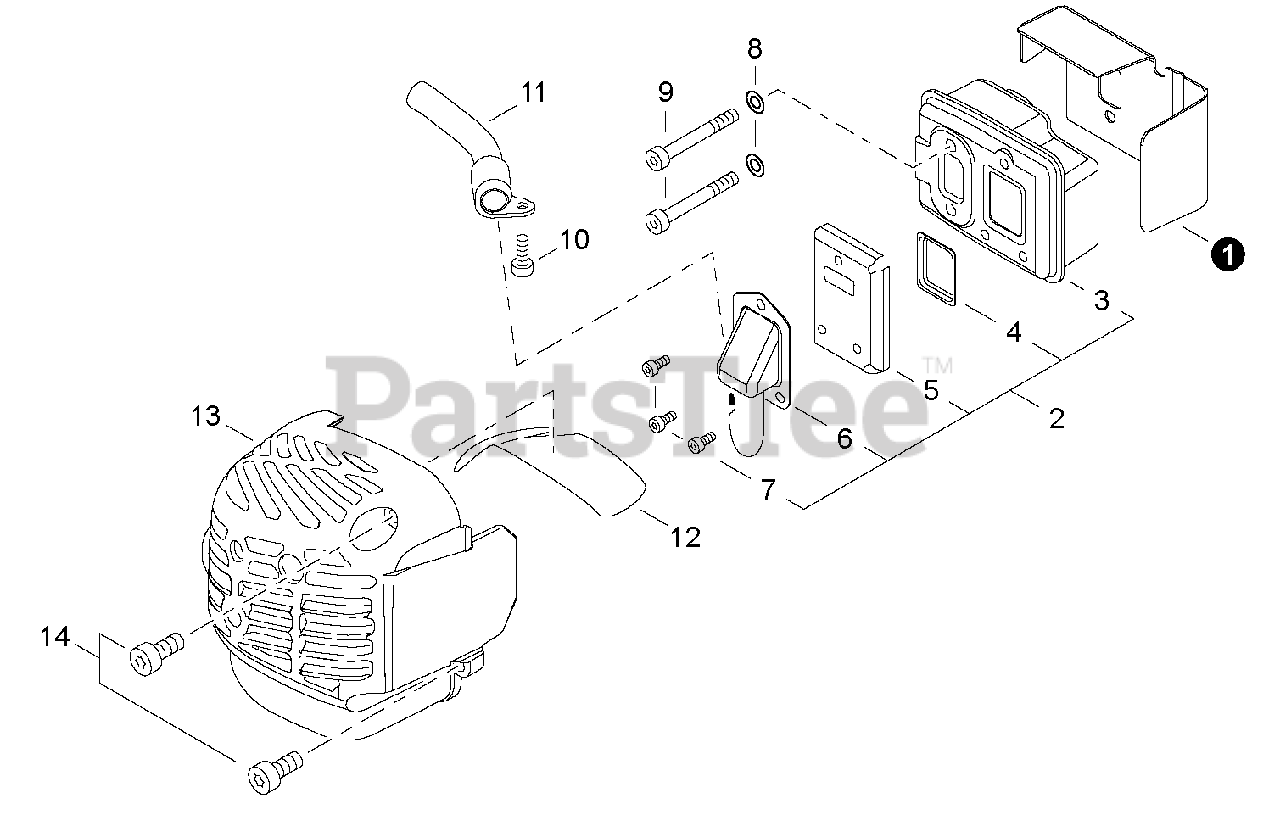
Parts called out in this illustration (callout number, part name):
1	SHIELD, EXHAUST
2	MUFFLER ASSY
3	MUFFLER
4	SCREEN, SPARK ARRESTOR
5	GASKET, EXHAUST
6	GUIDE, EXHAUST
7	SCREW - 4X8
8	WASHER - 5
9	SCREW - 5X55
10	SCREW - 5X10
11	GUIDE, EXHAUST
12	PLATE, INSULATOR
13	COVER, MUFFLER
14	SCREW - 5X16
